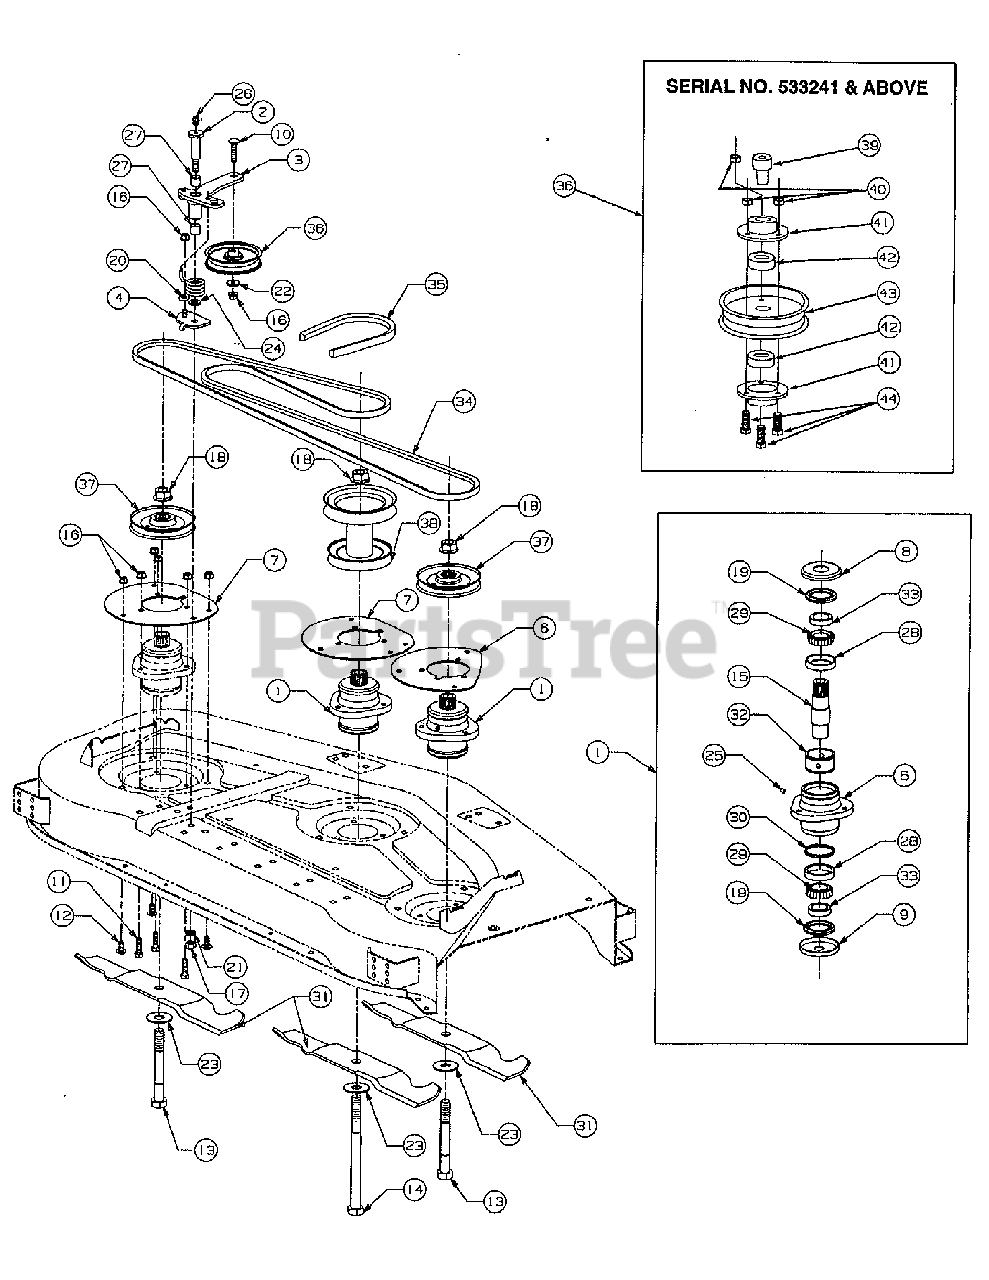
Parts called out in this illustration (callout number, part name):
1	Spindle Assembly, Complete
2	Bolt, Shoulder
5	Housing, Spindle
6	Plate, RH Cover
7	Plate, Cover
8	Cup, Top Spindle
9	Cup, Bottom Spindle
10	Bolt, Carriage, 3/8-16 x 1.75
11	Screw, Hex Cap, 3/8-16 x 1.25 Gr 5
12	Bolt, Sht Nk Carriage, 3/8-16 x .75 Gr 5
13	Bolt, Hex Hd Blade, 3/4-16 x 6.0
14	Bolt, Hex Hd Blade, 3/4-16 x 9.5
15	Shaft, Blade Spindle
16	Nut, Hex Flanged Lock, 3/8-16
17	Nut, Hex 7/16-14 Gr 5
18	Nut, Hex Flange 3/4-16
19	Seal, Oil
20	Spring, Torsion
21	Washer, Lock 7/16
22	Washer, Spec .378 x 1.0 x .125 Thk
23	Washer, Flat .781 x 2.0 x .105 Thk
24	Washer, Flat .469 x .875 x .105 Thk
25	Fitting, Lube
26	Fitting, Lube 90 Deg, 1/4-28 Tapper Thd
27	Bearing, Sleeve
28	Cup, Bearing
29	Cone, Bearing
30	Spacer, Bearing
31	Blade, Mower 18.5
31	Blade, Mower, Hard Coated 18.5
32	Spacer, Bearing Cup
33	Ring, Seal
34	Belt, Spindle A-Sect x 122.0
35	Belt, PTO B0Sect x 62.04
36	Pulley, Flat Idler
36	Pulley Assembly, Idler NLA
37	V-Pulley, 4.65 OD
38	Pulley, Deck, 5.07 OD & 5.75 OD
39	Spacer, ShoulderNLA
40	Nut, Hx Insrt Lock
41	Cup, Bearing
42	Bearing, Ball
43	Pulley, Flat Idler NLA
44	Screw, Hex Cap, 1/4-20 x .62 Gr 5
